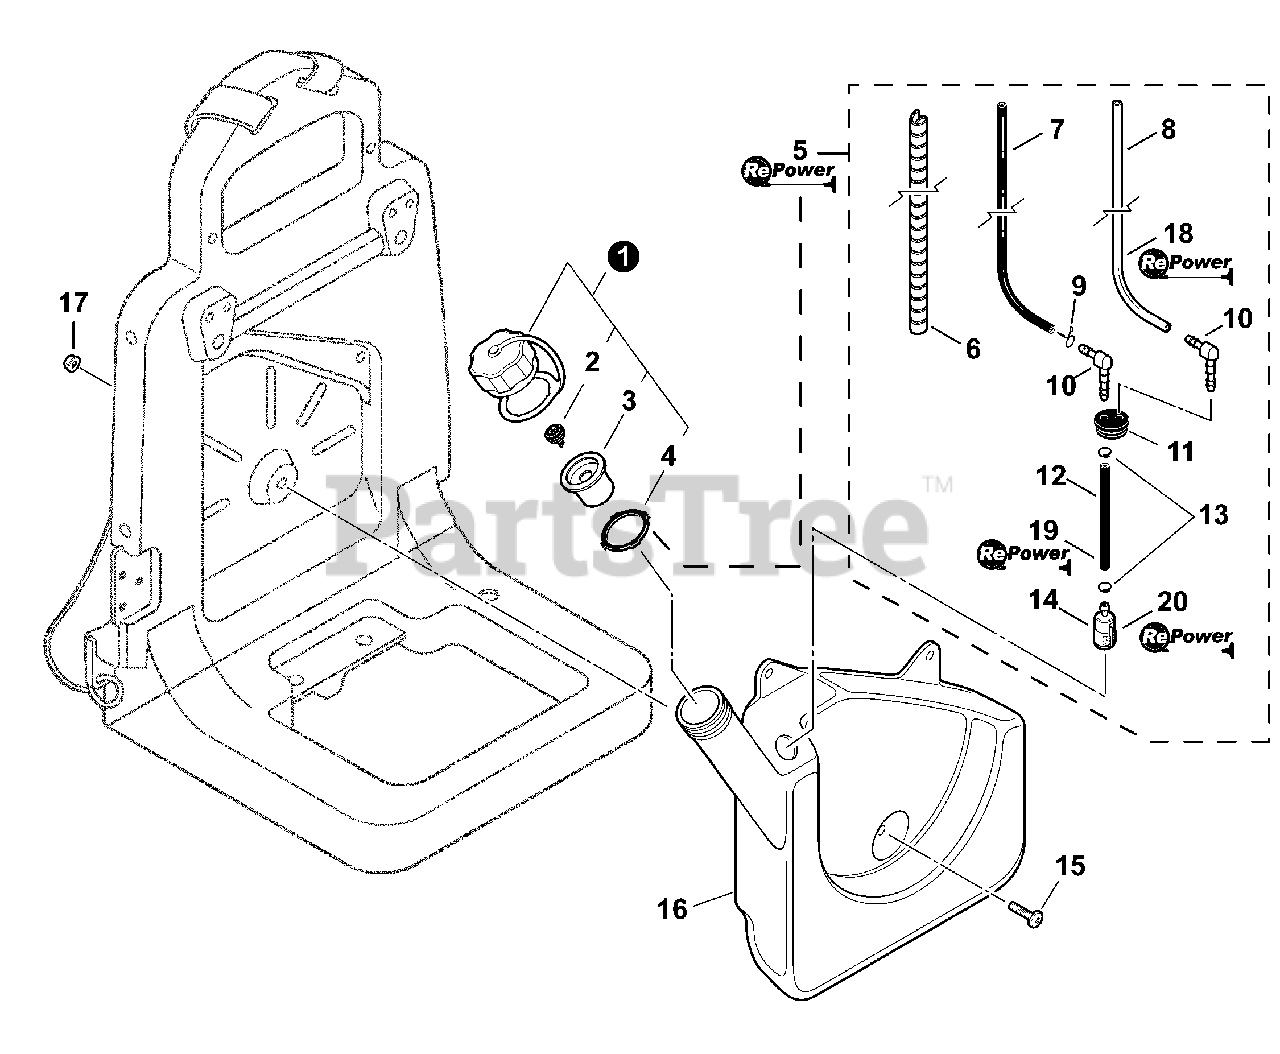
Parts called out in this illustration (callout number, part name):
1	CAP ASSY, FUEL
2	VENT ASSY
3	HOLDER, VENT
4	GASKET, FUEL CAP
5	FUEL SYSTEM KIT
6	TUBE, SPIRAL
7	PIPE, FUEL - 3×5×470 - BLACK
8	PIPE, FUEL - 3×6×470 - CLEAR
9	CLIP, SPRING Ø5.2
10	CONNECTOR, PIPE
11	GROMMET, FUEL
12	PIPE, FUEL 3×6×280 MM
13	CLIP Ø6.5 MM
14	FILTER, FUEL
15	SCREW 5×20
16	TANK, FUEL
17	NUT, FLANGE M5
18	BULK PIPE - 3×6 MM CLEAR (4 PIECES×2 M)
19	BULK PIPE - 3×6 MM BLACK (4 PIECES×2 M)
20	TUNE-UP KIT - REPOWER
